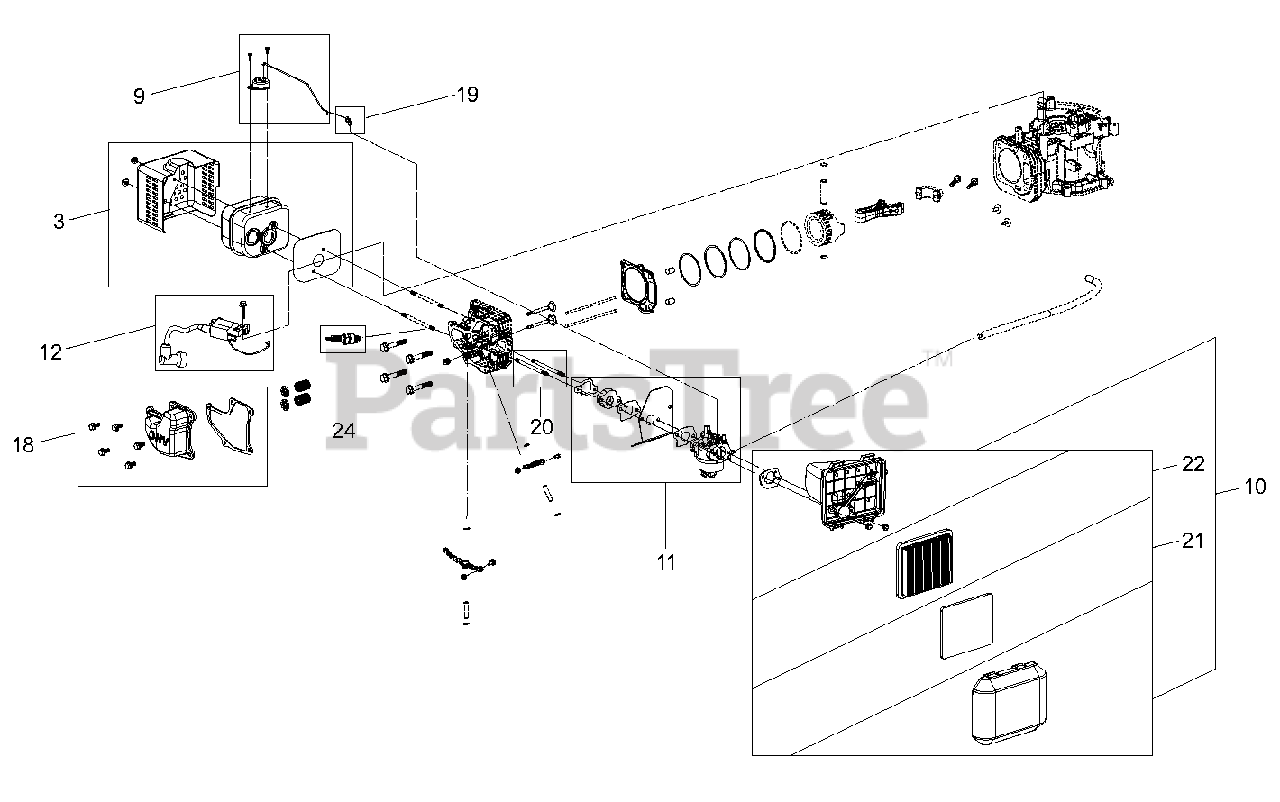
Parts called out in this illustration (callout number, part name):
1	AIR VANE CHOKE KIT
2	GOVERNOR ARM KIT
3	MUFFLER AND SHIELD KIT
4	FLYWHEEL AND FAN KIT – RECOIL START
5	KIT BRAKE ASSEMBLY RECOIL
7	KIT ARIENS STYLE
8	KIT FLYWHEEL SHIELD
9	THERMAL CHOKE CONTROL KIT
10	KIT-AIR CLEANER ASM, 2 HINGE
11	CARBURETOR COMPLETE KIT
12	IGNITION COIL KIT
18	KIT-VALVE COVER (1P65FA)
19	LOCK-THROTTLE
20	STUD-INTAKE
21	AIR FILTER, FOAM PRE-FILTER
22	AIR FILTER ELEMENT
23	FUEL LINE WITH STRAINER
24	SPARK PLUG
25	OIL FILTER TUBE/CAP
26	GAS CAP WITH CANISTER
27	FUEL TANK
28	RECOIL ASSEMBLY
